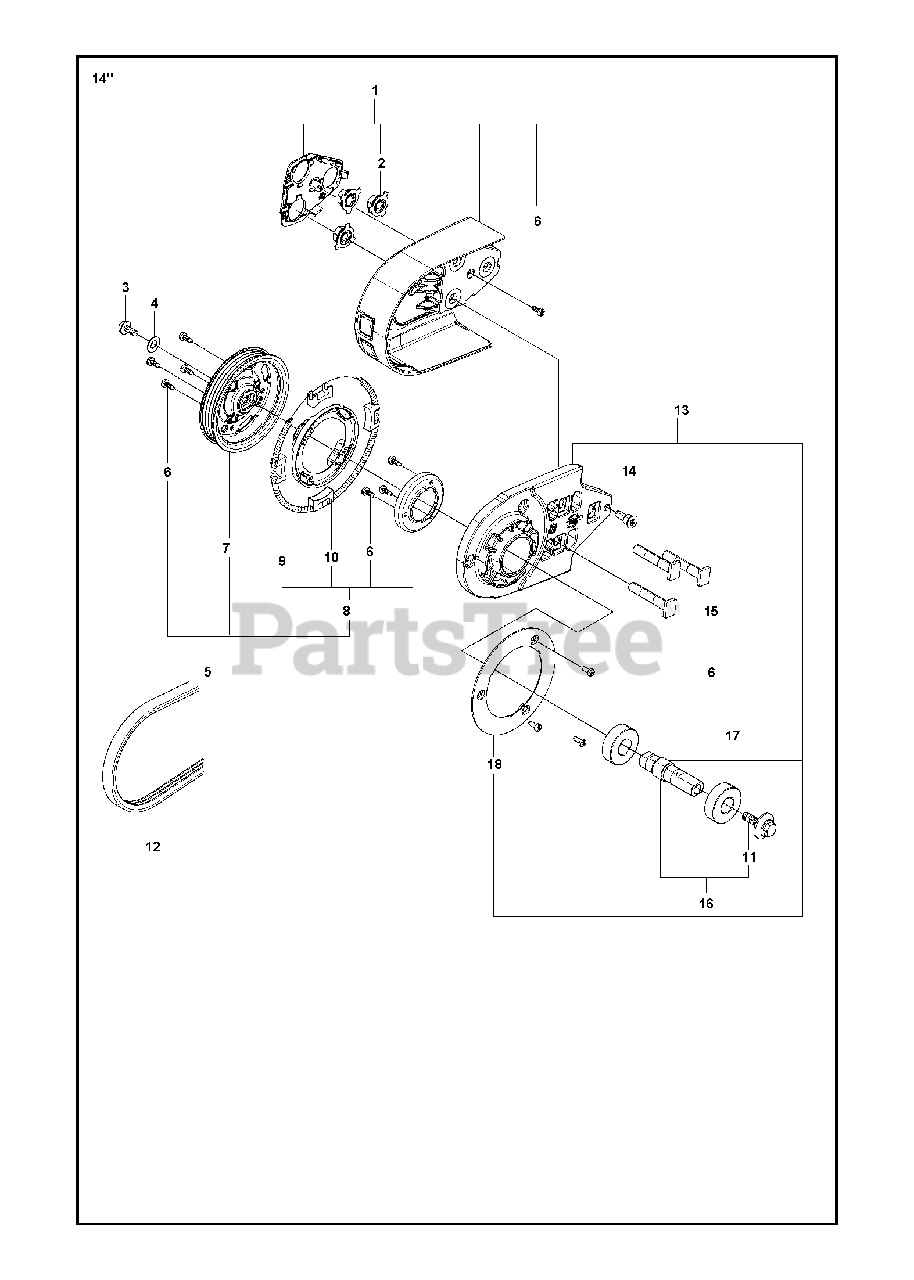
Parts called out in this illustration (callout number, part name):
6	SCREW CITXPANT
13	BEARING HOUSING ASSY"14"""
17	BALL BEARING
